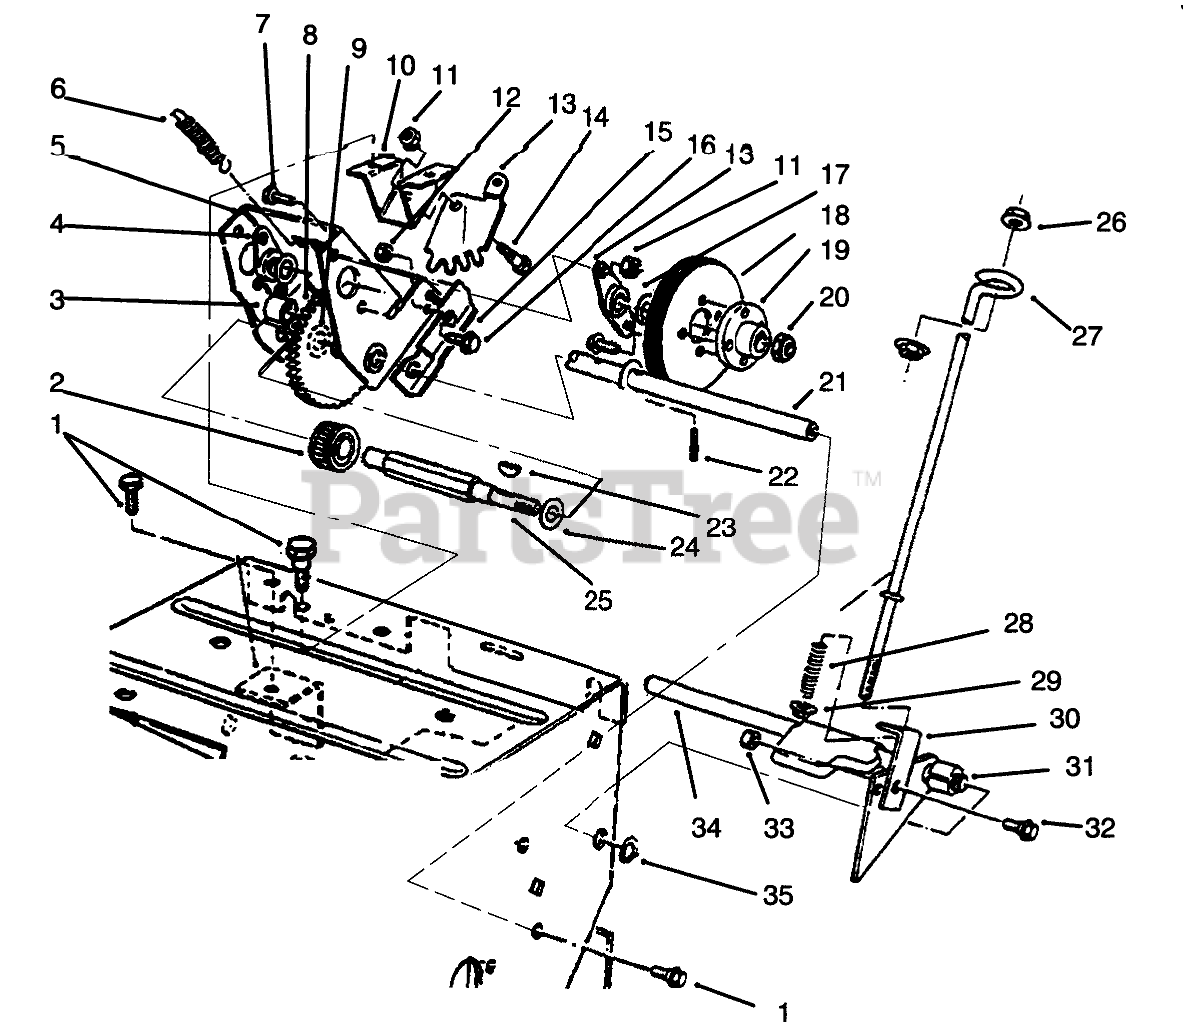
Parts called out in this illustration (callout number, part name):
1	SCREW-HWHTF
2	PINION
3	5/8ID X 1LG BUSHING
4	BEARING-WHEEL, FRICTION
5	BRACKET-SLIDING
6	SPRING-TRACTION
7	SCREW-HH
8	Intermediate Gear & Bushing (Incl. Ref. #4)
9	WASHER-SPECIAL
10	MOUNT-LEVER
11	NUT-LOCK, NI
12	NUT-LOCK, NI
13	GEAR-QUADRANT
14	BOLT-SHOULDER
15	CAM-RECEIVER
16	SCREW-HH
17	WASHER-THRUST
18	WHEEL-FRICTION
19	HUB-WHEEL, FRICTION
20	NUT-LOCK, NI
21	SHAFT-PIVOT
22	PIN-SPRING
23	KEY-WOODRUFF
24	WASHER-FLAT
25	SHAFT-WHEEL, FRICTION
26	NUT-HF
27	ROD-TRACTION, LOWER
28	SPRING
29	NUT-HHF
30	BRACKET-TRACTION
31	SPACER
32	SCREW
33	NUT-LOCK, NI
34	Traction Engagement Asm.
35	RING-RETAINING
